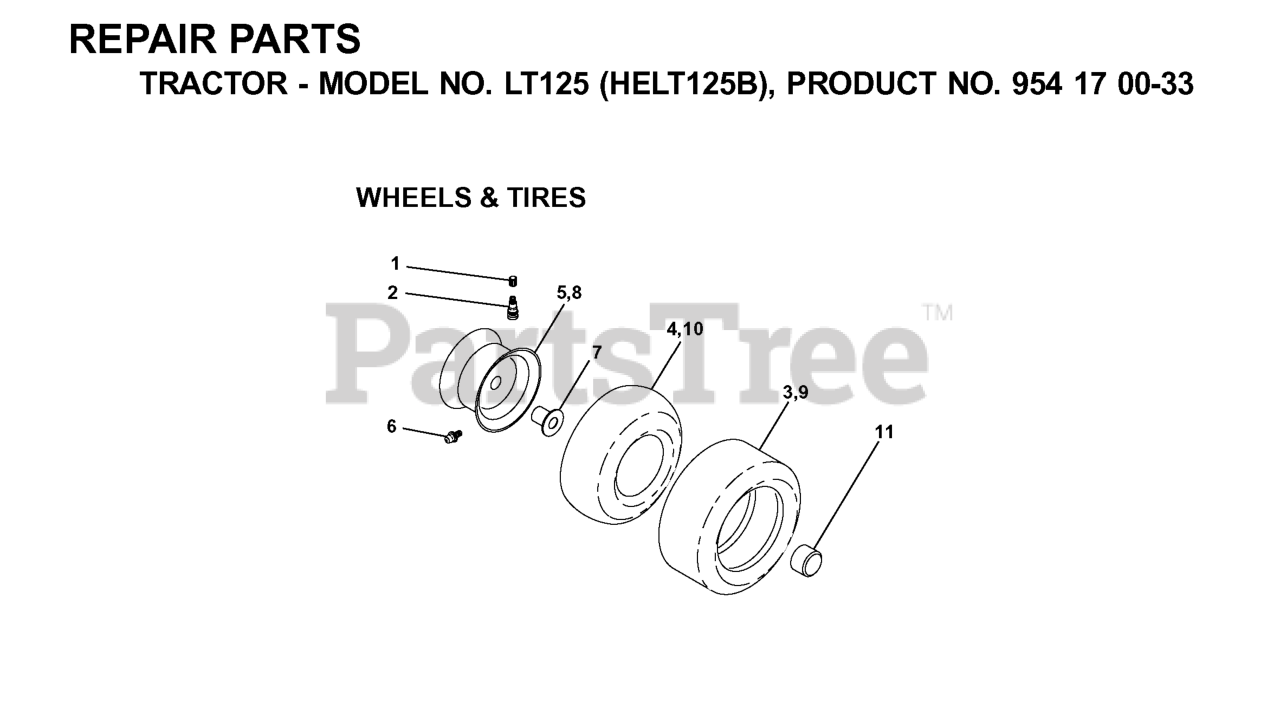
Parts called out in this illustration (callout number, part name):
2	VALVE STEM LT
3	TIRE HEAVY DUTY
4	TUBE.5.3/4.5/6
5	RIM ASM 6" FRONT SILVER
6	FITTING LT
7	BEARING T
8	RIM ASM 8" REAR SILVER
9	TIRE
10	TUBE
11	CAP, AXLE BLK
